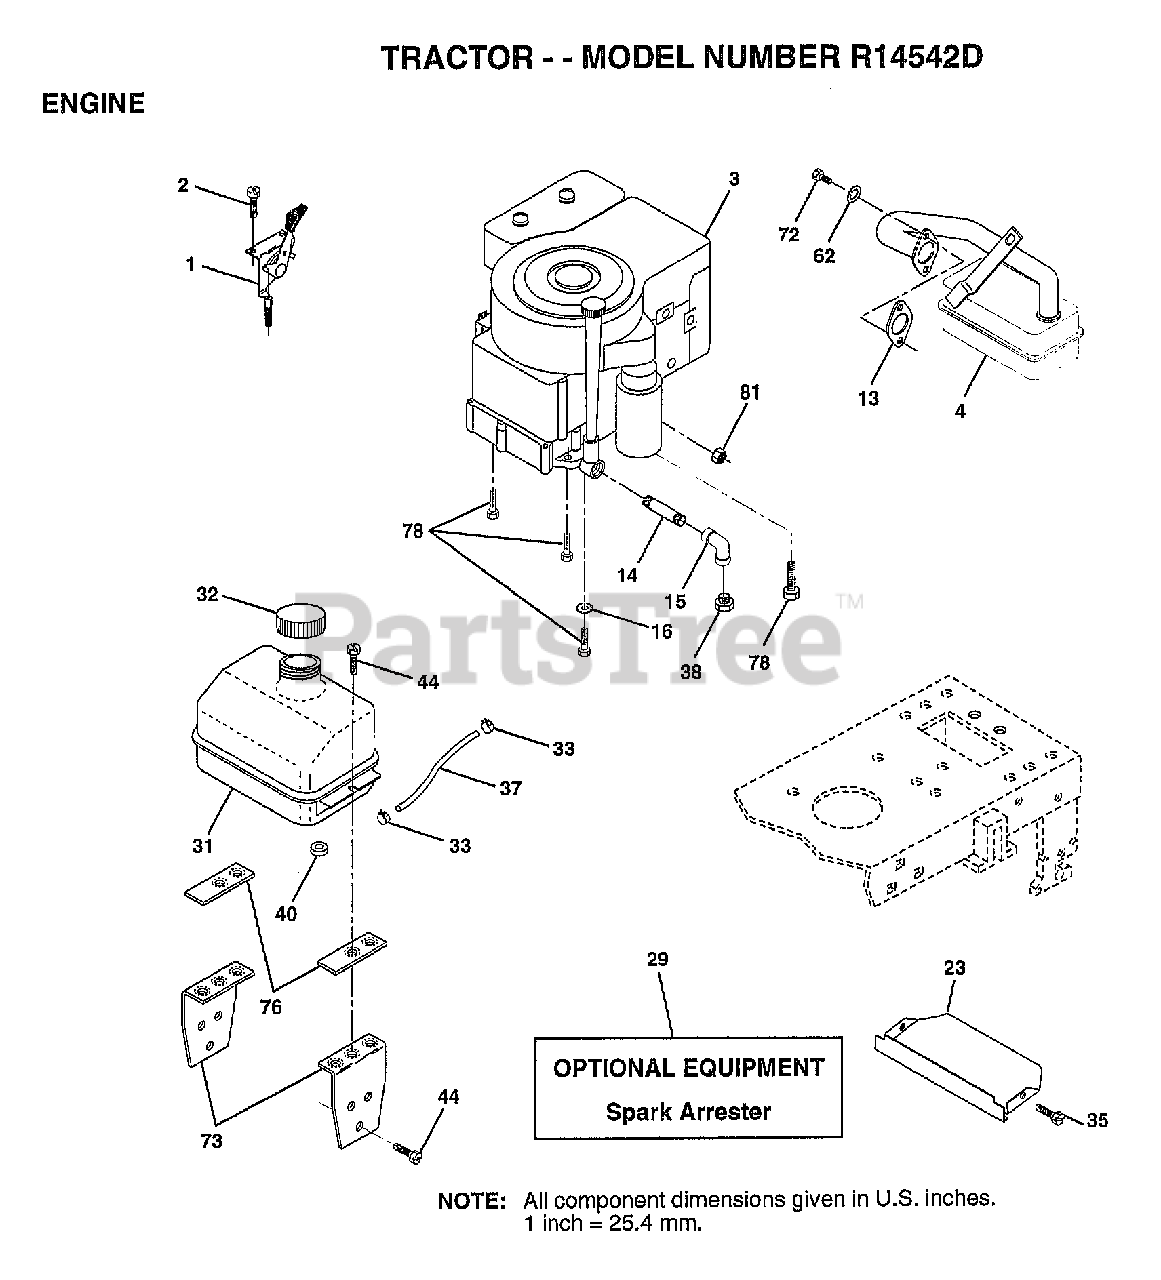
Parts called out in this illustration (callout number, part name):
1	THROTTLE CONTROL
2	SCREW LT
4	MUFFLER
13	GASKET ENG 1 313 LD TIN PLATED
14	PIPE NIPPLE
15	ELBOW
16	LOCKWASHER
23	SHIELD.BRN/DBR.GD
31	TANK.FUEL.LT.
32	CAP ASM FUEL
33	HOSE CLAMP
35	SCREW
37	LINE FUEL
44	SCREW
62	LOCKWASHER
72	SCREW
73	BRKT FUEL TANK T
76	"CLAMP,FUEL TANK T"
78	SCREW
81	NUT
